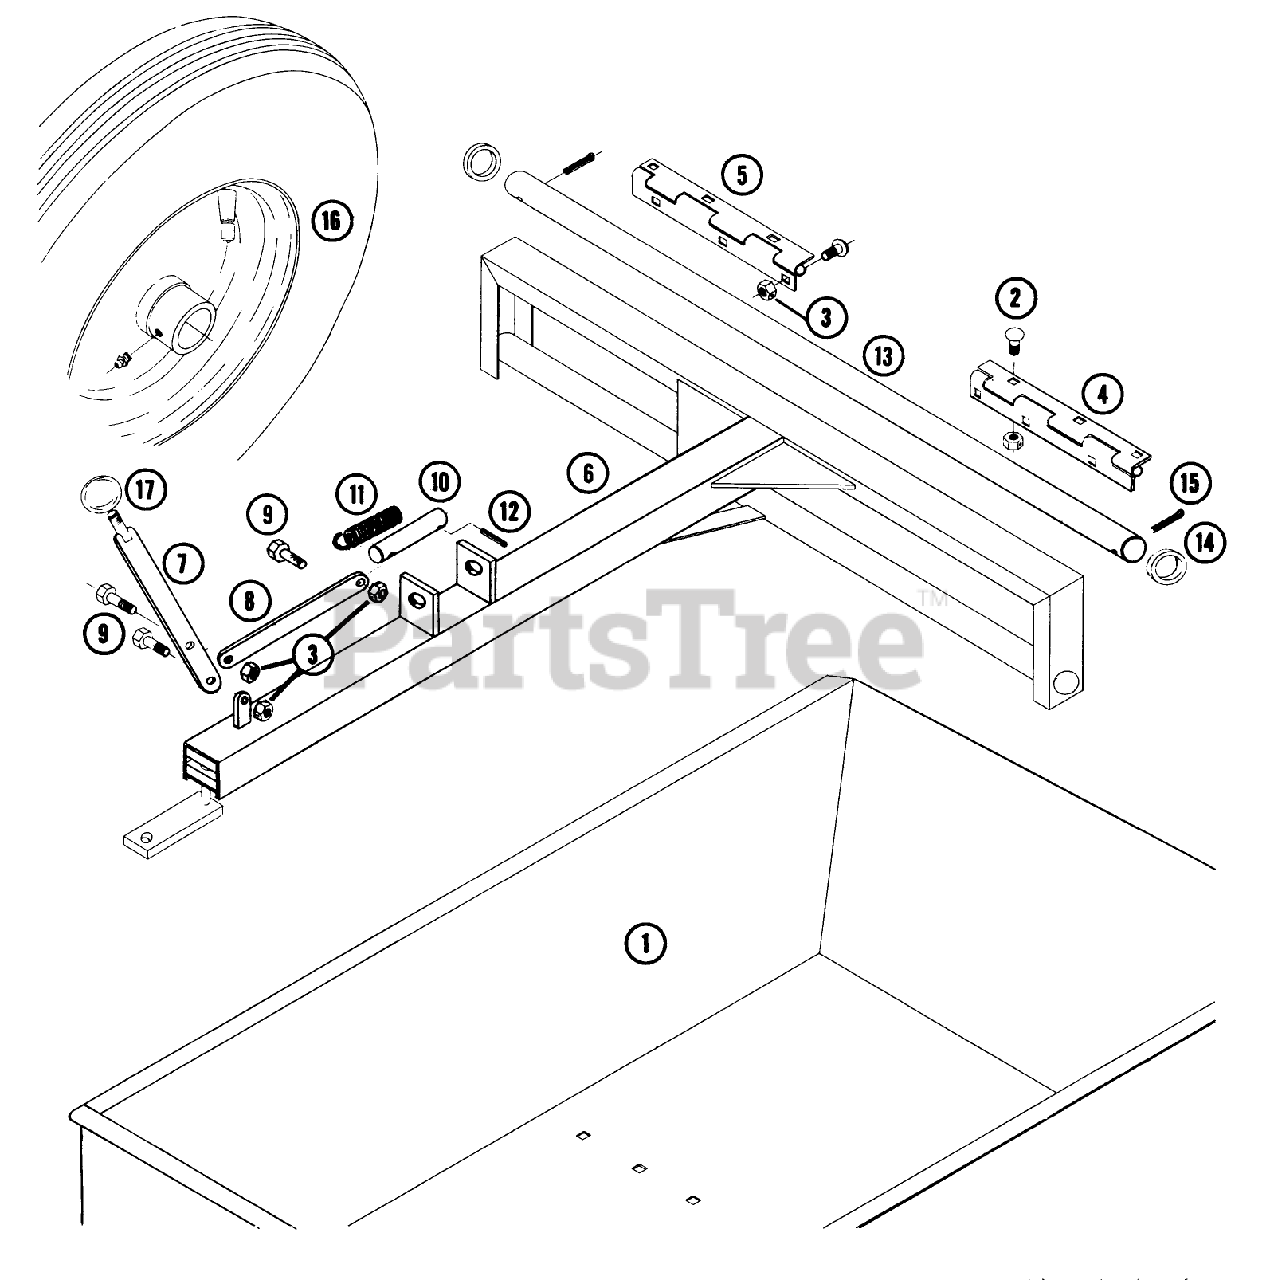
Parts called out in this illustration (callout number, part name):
1	Bed Ass-y. W/A
2	Carriage Bolt 1/4-20 x 5/8
3	1/4-20 Lock Nut
4	Trailer Hinge L.H.
5	Trailer Hinge R.H.
6	Frame Ass-y. W/A
7	Handle Ass-y. W/A
8	Latch Bar
9	Hex Hd. Cap Screw
10	Index Pin
11	SPRING-COMPRESSION
12	Cotter Key
13	Axle
15	Cotter Pin
